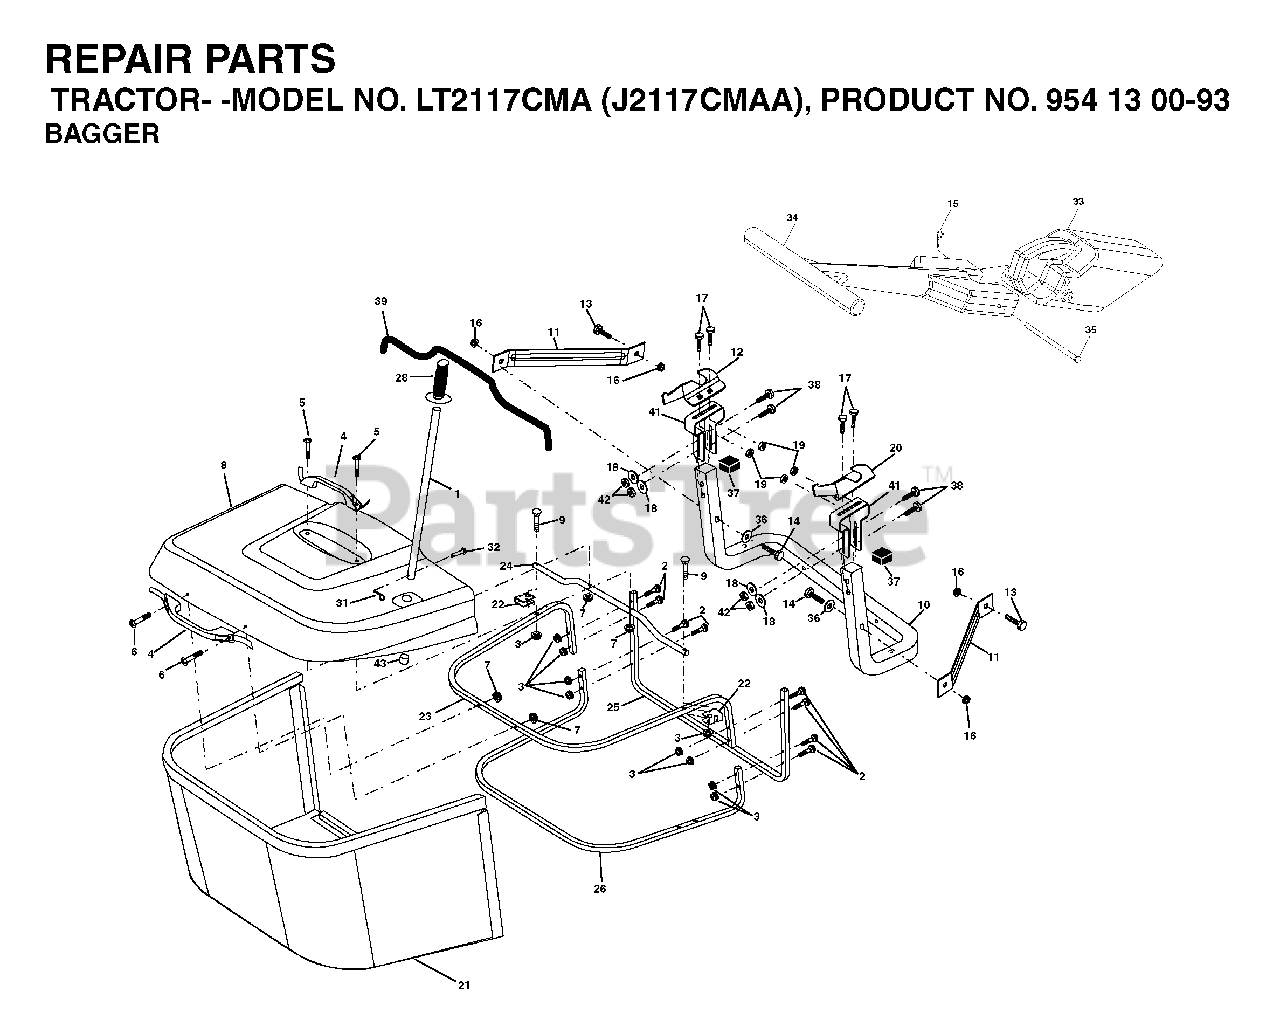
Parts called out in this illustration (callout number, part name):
1	TUBE HANDLE
3	NUT T
5	SCREW.PAN.HEAD
11	BRACKET
14	BOLT-HEX EAK
15	RETAINER-SPRNG RB
16	NUT LOCK FLG 3/8-16 UNC
17	BOLT
18	WASHER M
19	NUT LOCK HEX FLANGE 5/16-18
20	BRACKET
21	GRASS BAG
22	BRACKET
23	TUBE
24	TUBE
26	TUBE
28	GRIP.HANDLE.BLACK
31	RETAINER M
32	RIVET,DRILLED
33	MULCH PLUG, CTH150
35	PIN
36	WASHER
38	BOLT.5/16-18X2.5
41	BRKT, BAGGER
42	NUT.71038.31-18.HEX.NYLOCK
43	PLUG, TUBING END
